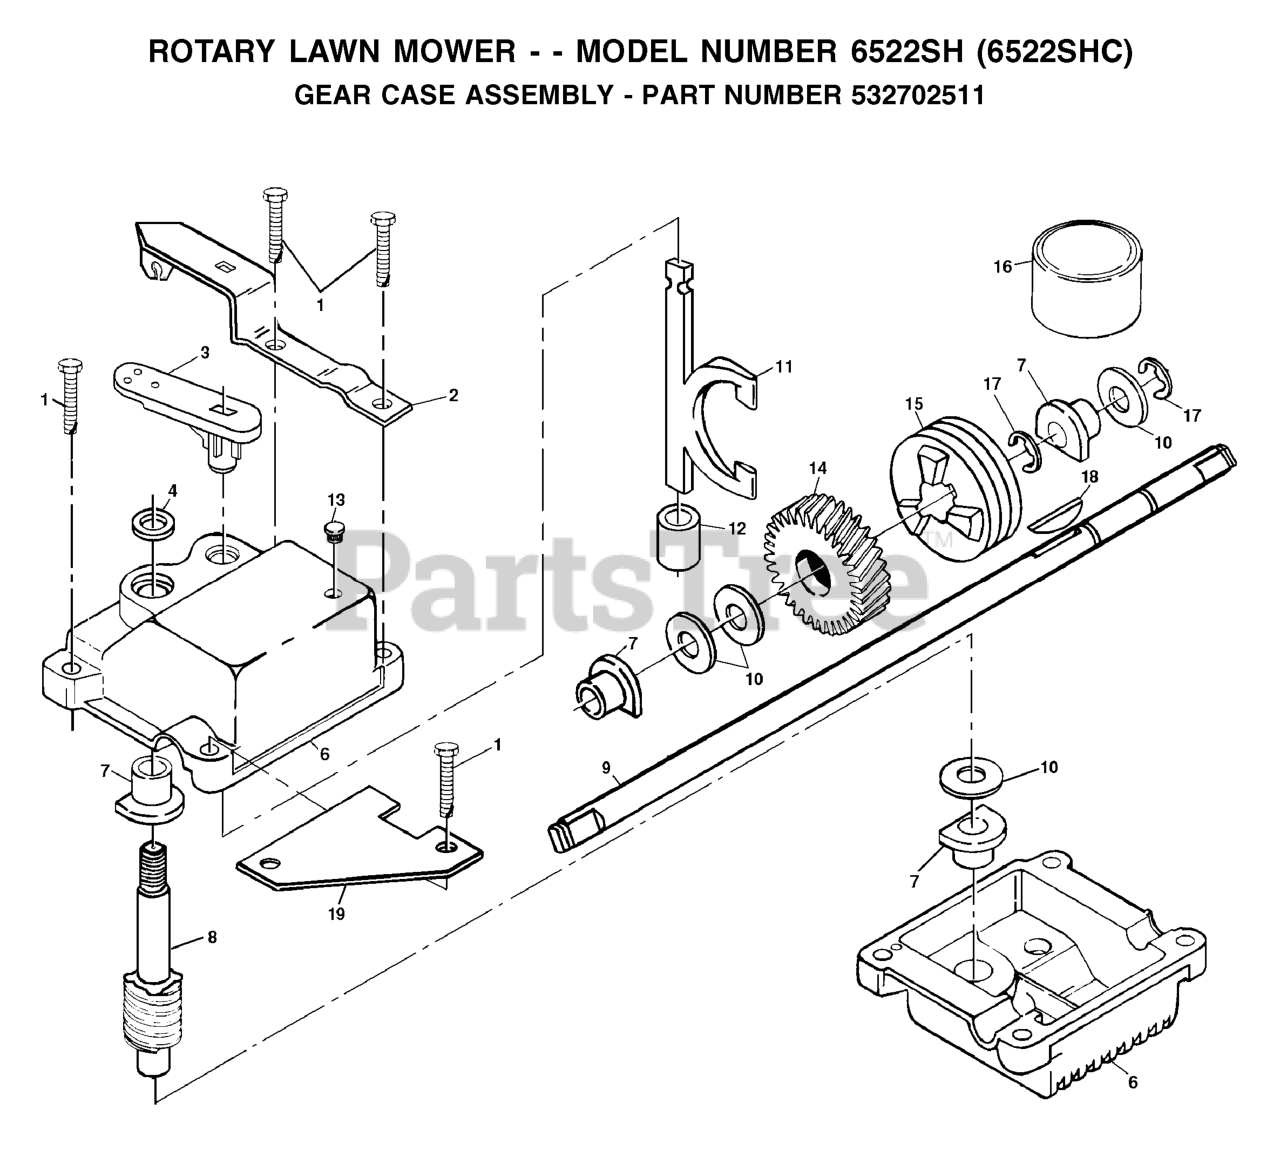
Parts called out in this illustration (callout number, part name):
1	SCREW
2	BRACKET
8	WORM SHAFT
9	DRIVE SHAFT, 20-5/8"
10	THRUST WASHER
11	YOKE.VIBRATORY FINISH.
13	PLUG.AUGER.GEAR.BOX.SNOW
14	GEAR.HELICAL
15	CLUTCH JAW
16	GREASE
18	HI PRO KEY
19	BRACKET SPRING
